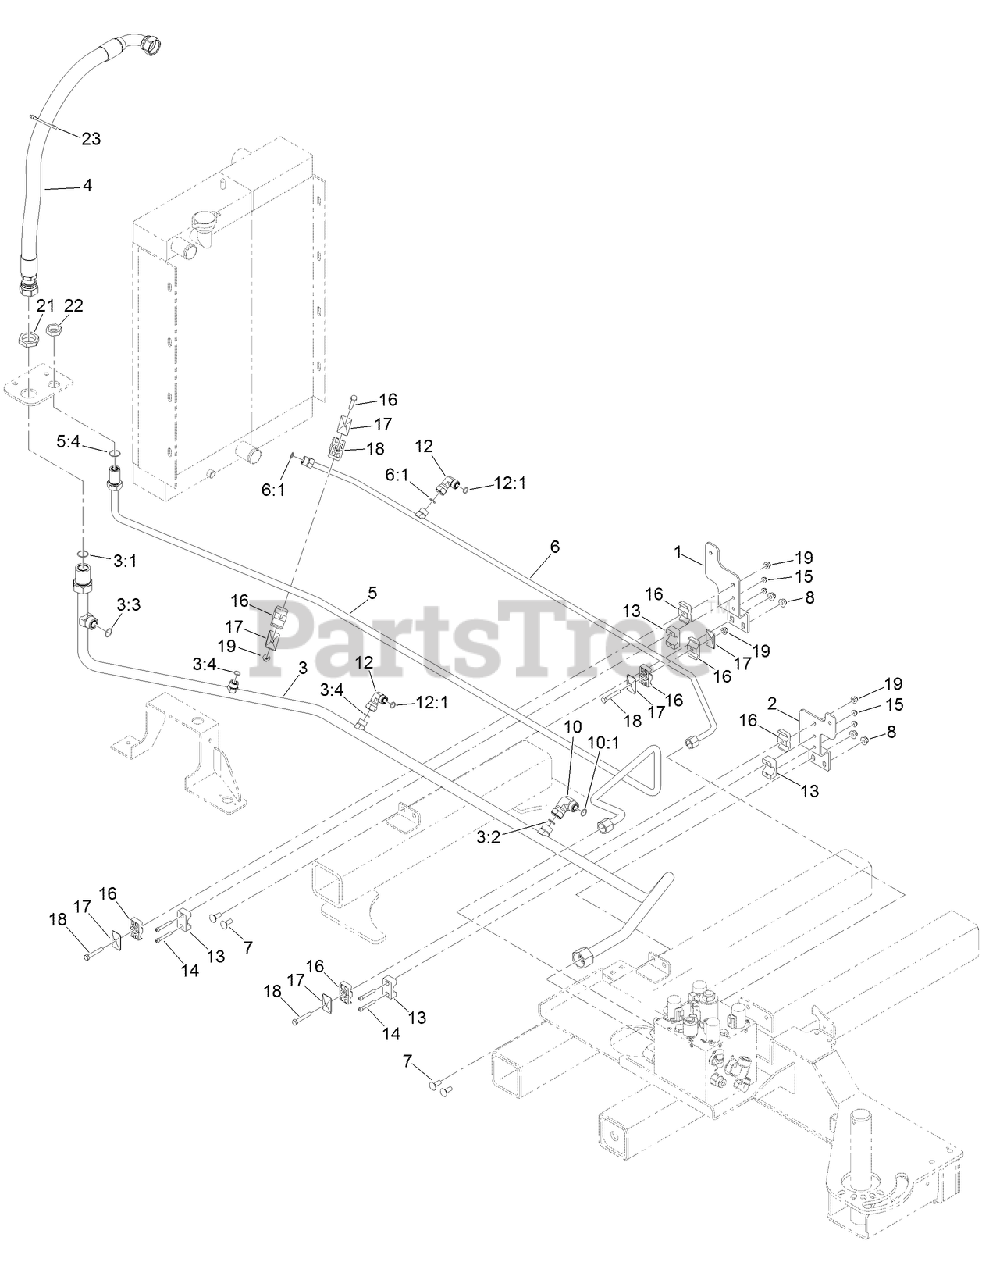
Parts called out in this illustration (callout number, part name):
1	BRACKET-HANGER, REAR
2	BRACKET-HANGER, FRONT
3	TUBE ASM
3:1	O-RING
3:2	O-RING
3:3	O-RING
3:4	O-RING
4	HOSE ASM-HYD
5	TUBE ASM-HYD
5:4	O-RING
6	TUBE ASM-HYD
6:1	O-RING
7	SCREW-HH
8	NUT-HF, NI
10	FITTING-HYD-90
10:1	O-RING
12	FITTING-HYD
12:1	O-RING
14	SCREW-HSH
15	NUT-HF
16	CLAMP-TUBE
17	COVERPLATE
18	SCREW-HH
19	NUT-HF, NI
21	NUT-BULKHEAD
22	NUT-LOCK, BULKHEAD
23	TIE-CABLE
